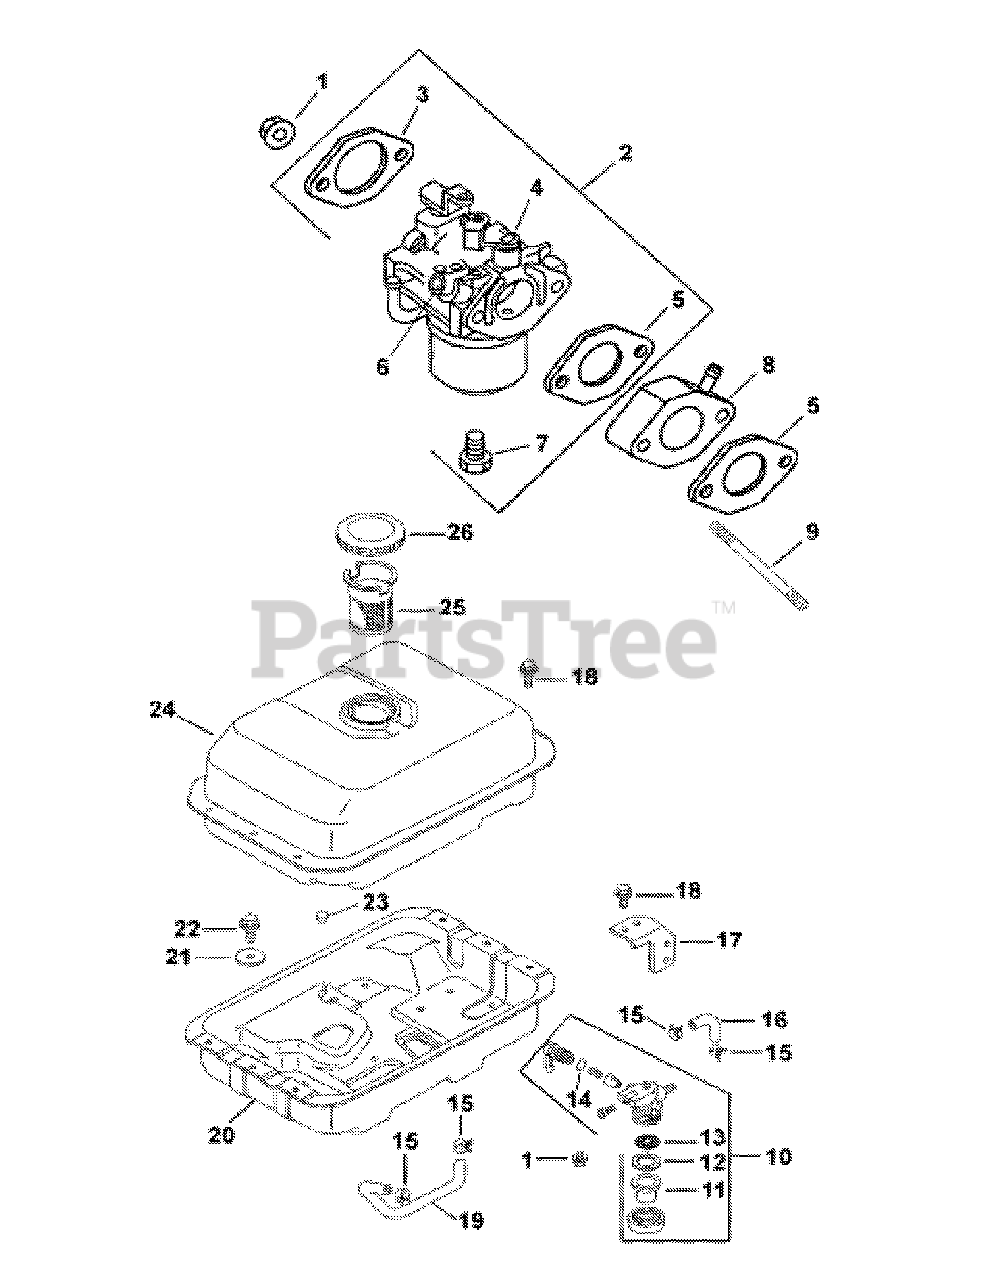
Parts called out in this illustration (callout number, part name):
1	Air Cleaner Nut
2	Carburetor w/Gasket Kit
3	Air Cleaner Base Gasket
5	Carburetor Gasket
6	Carburetor Adjusting Cap
7	Float Bowl Screw
8	Intake Manifold
9	Carburetor Stud
10	Fuel Shut-off Valve Assy.
12	Fuel Strainer Gasket
13	Filter Screen
17	Fuel Valve Bracket
25	Fuel Tank Strainer
26	Fuel Tank Cap
